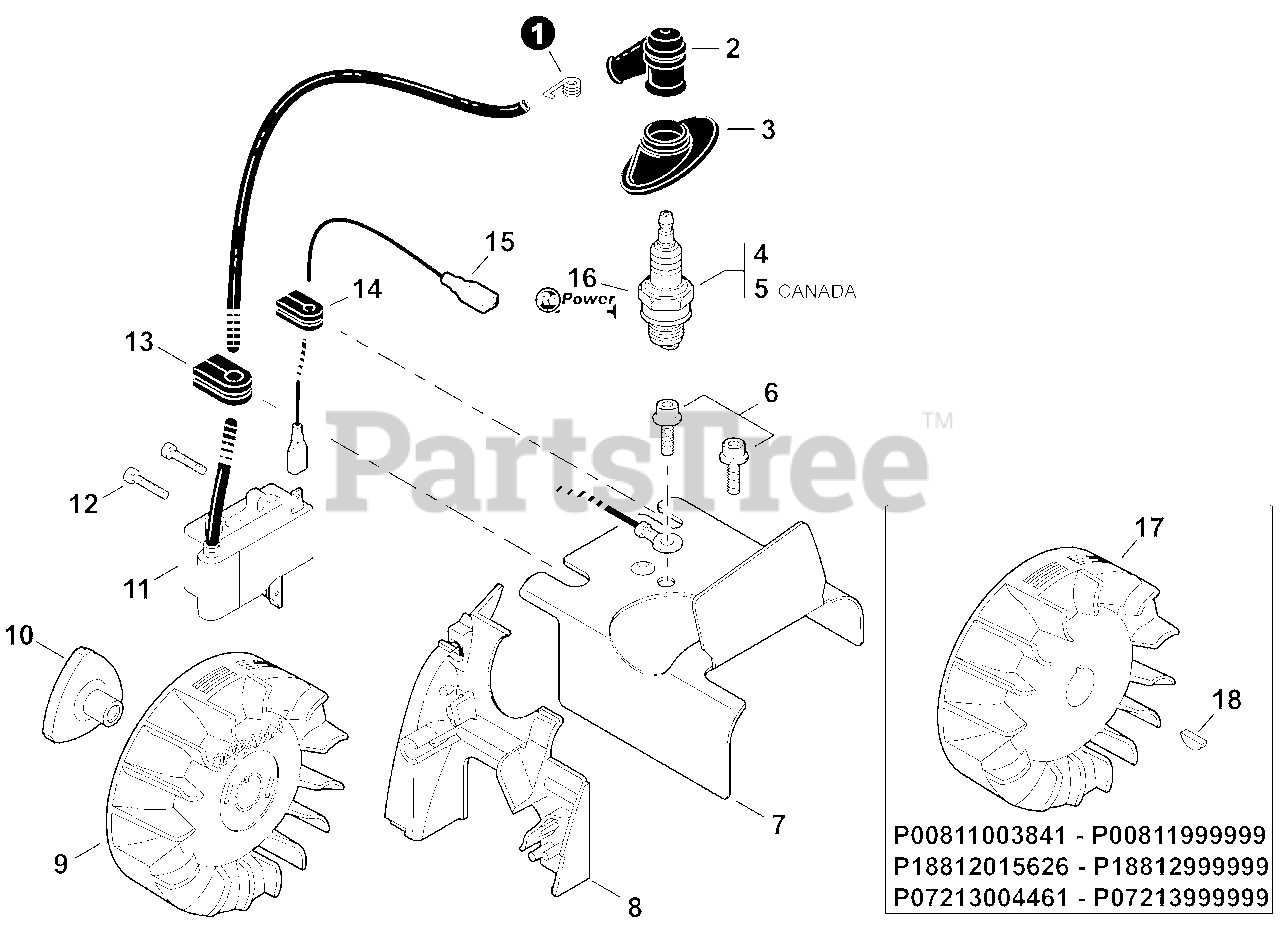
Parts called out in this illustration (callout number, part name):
1	TERMINAL, SPARK PLUG
2	CAP, SPARK PLUG
3	COVER, DUST
4	SPARK PLUG - BPM8Y
5	SPARK PLUG - BPMR8Y
6	BOLT 5×8
7	COVER, CYLINDER
8	COVER, CYLINDER - PLASTIC
9	FLYWHEEL
10	HUB, FAN
11	COIL, IGNITION
12	BOLT 4×20
15	LEAD - IGNITION
16	TUNE-UP KIT - REPOWER
17	FLYWHEEL
18	KEY, WOODRUFF
